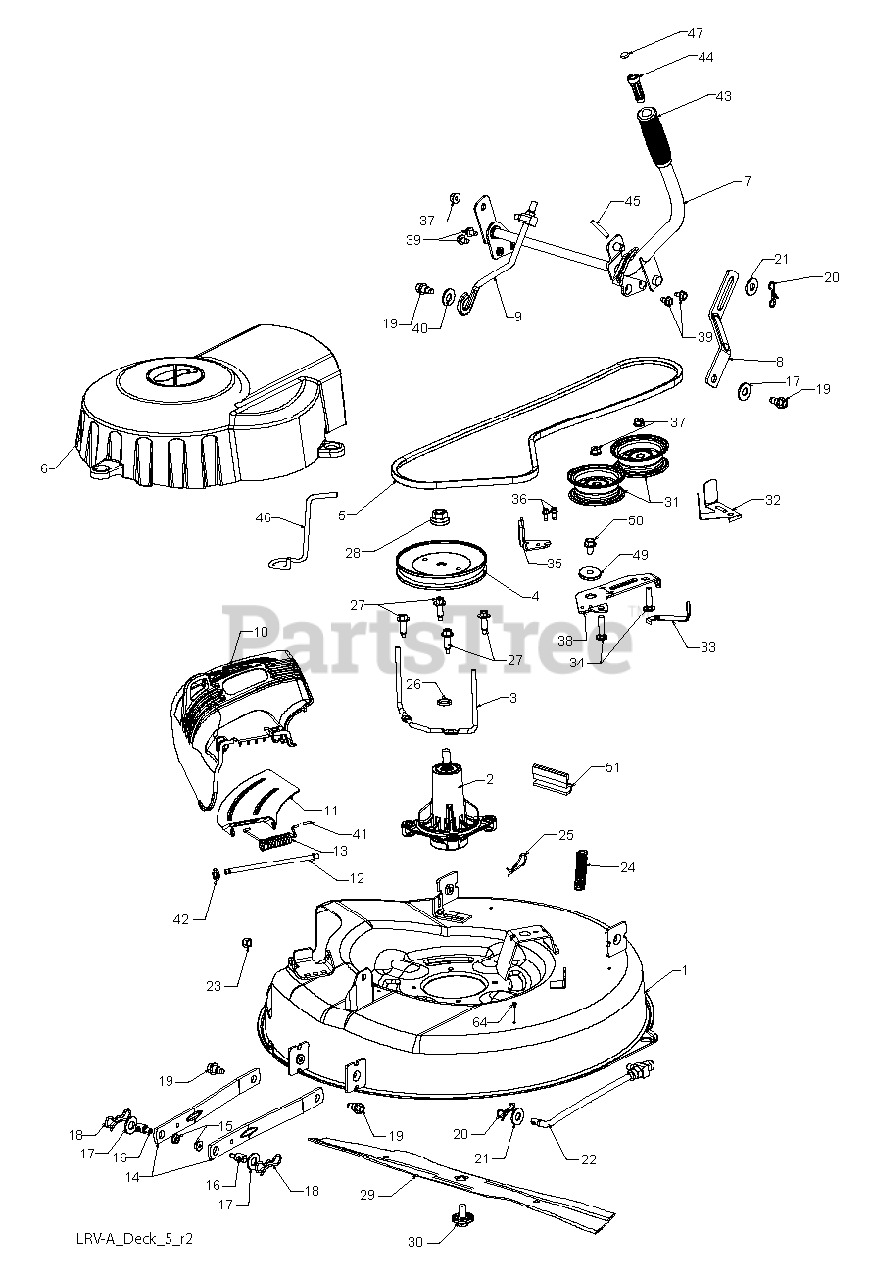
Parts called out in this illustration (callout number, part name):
1	DECK, 26"
2	MANDREL.ASM.SUB-NON.GR
3	KEEPER.BELT.MANDREL.PULLEY
4	PULLEY.MANDREL
6	COVER, MANDREL
7	LIFT.ASM.DECK.LRV
8	LINK, DECK LIFT
9	LINK.ASM.LIFT.ADJUSTABLE
11	SUPPORT, DEFLECTOR
12	ROD.HINGE
13	SPRING.TORSION.DEFLECT
14	ARMS.SUSP.MOWER.REAR.SRD
15	NUT LOCK HEX FLANGE 5/16-18
16	STUD.FASTNER.W/ANTI-ROTATE
17	WASHER.CLEAR.ZINC
18	PIN.COTTER.7/16.BOW TI.
19	BOLT.SHOULDER
20	PIN.COTTER.5/16.BOW TI
22	LINK.ASM.TOP.DECK.LRV
23	NUT LOCK FLG 3/8-16 UNC
24	SPRING.EXTENSION.DECK.LRV
26	WASHER.SPACER.MANDREL
27	SCREW, WASHER HEAD
28	NUT.FLANGE.LOCK.TOP
29	BLADE.26"
30	BOLT.WASHER.ASM.7/16-2
31	PULLEY.IDLER.48"PRIMARY
32	GUARD, BELT
33	KEEPER BELT
34	BOLT.3/8-16X1.50
35	ARM BRAKE MOWER RH
36	SCREW.1/4-20X5/8
37	NUT LOCK FLG 3/8-16 UNC
38	ARM, IDLER
39	SCREW LT
40	WASHER
41	CAP-SLEEVE LT
42	NUT PUSH M
43	GRIP HANDLE
44	PLUNGER.ASM.LRV
45	PIN GROOVE.
46	KEEPER.BELT
47	PLUNGER BUT KIT
49	SPACER.RETAINER
50	SCREW 3/8-16X1
51	BUMPER.HOOD.TEX.HUSQVARNA
64	SCREW 3/8-16X1/2
